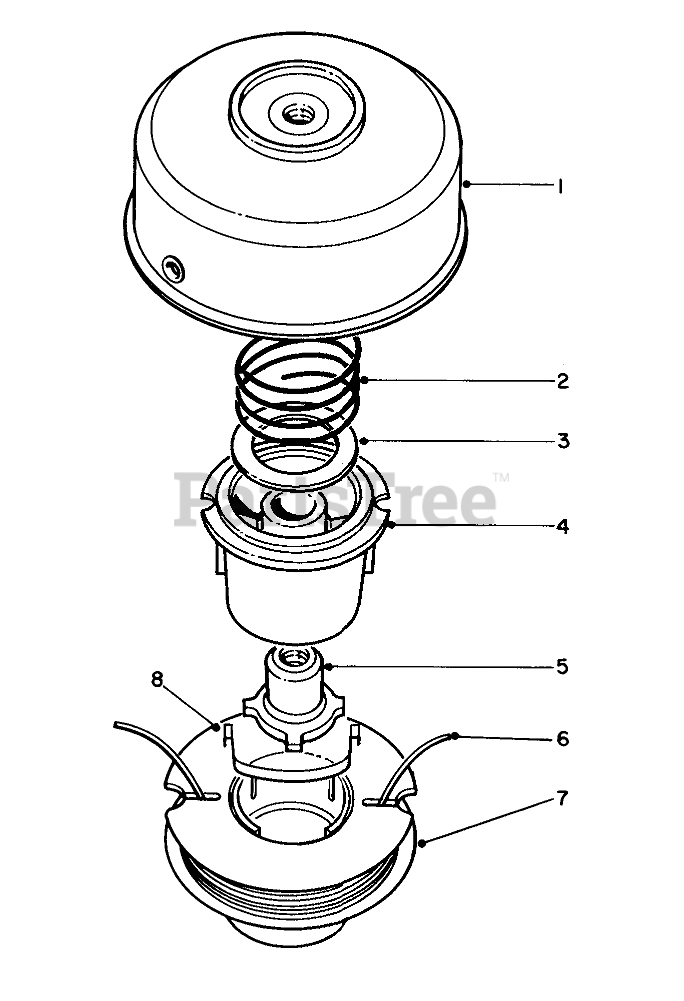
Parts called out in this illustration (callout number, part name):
1	ASM - TRIMMER DRUM & EYELET
2	SPRING
3	WASHER-FLAT
4	SPOOL CORE
5	LH DRIVER
6	REPL LINE PKG
7	Spool Housing
8	SADDLE-SPOOL CAP
